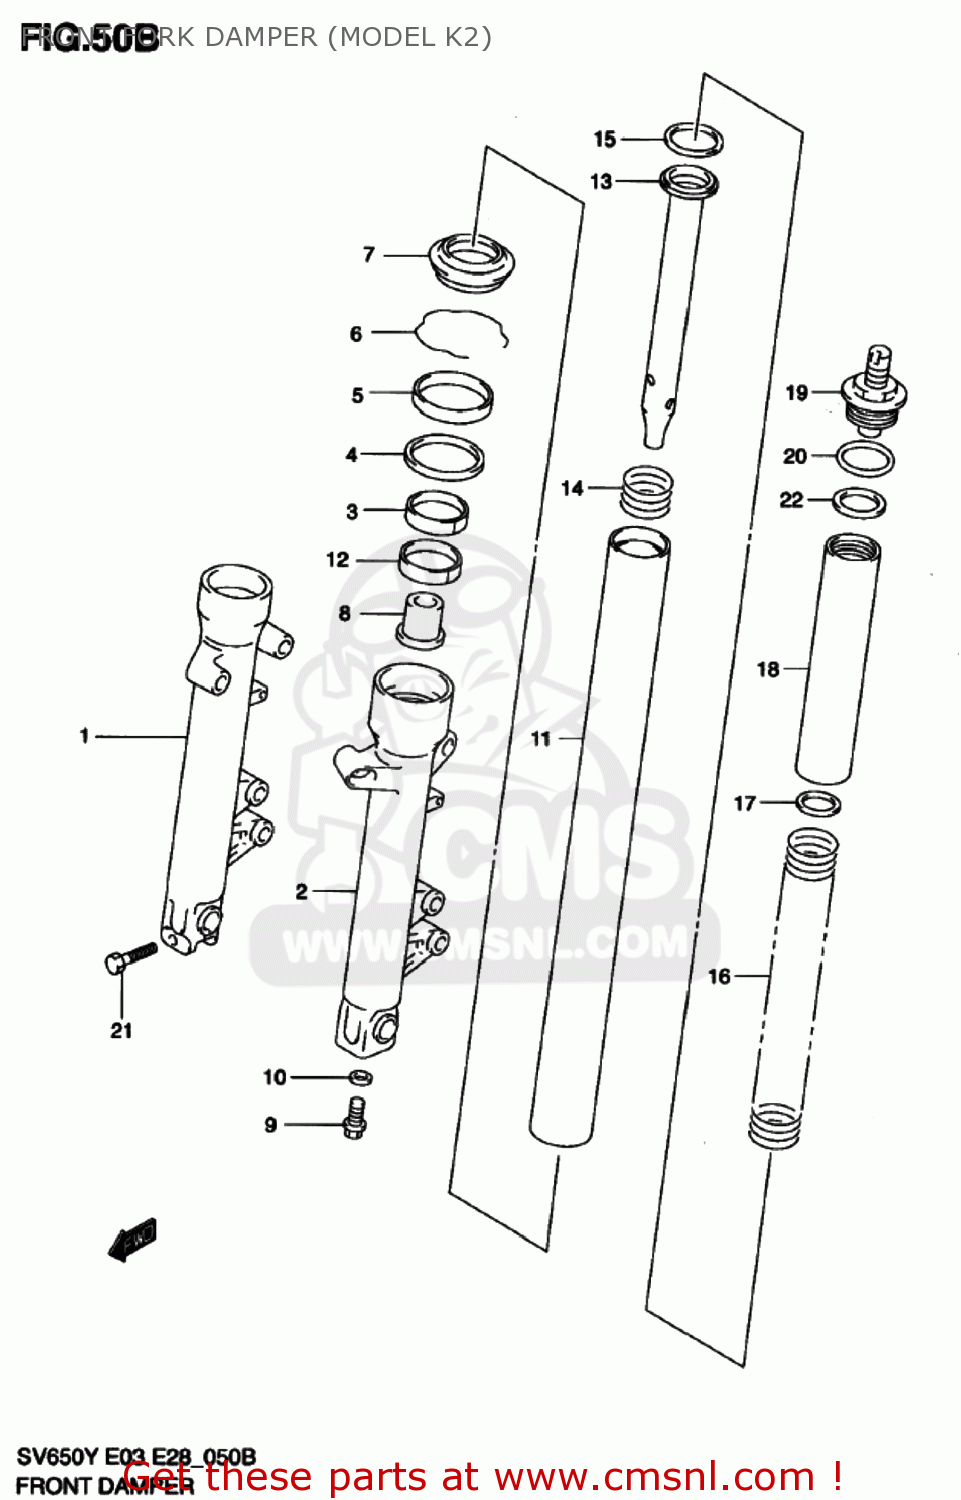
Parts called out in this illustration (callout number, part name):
1	TUBE,OUTER,R
2	TUBE,OUTER,L
3	METAL,SLIDE
4	WASHER,FORK OIL SEAL
5	SEAL,OIL
6	RING,OIL SEAL STOPPER
7	SEAL,DUST
8	PIECE,OIL LOCK
9	BOLT,FORK CYLINDER(10X25)
10	GASKET (NAS)
11	TUBE,INNER
12	PISTON
13	CYLINDER
14	SPRING,REBOUND
15	RING,PISTON
16	SPRING,FR
17	WASHER(22.5X35.9X1.6)
18	SPACER,SPRING
19	CAP ASSY,FORK
20	O RING(D:3.5,ID:31.7)
21	BOLT
22	WASHER,UPR
